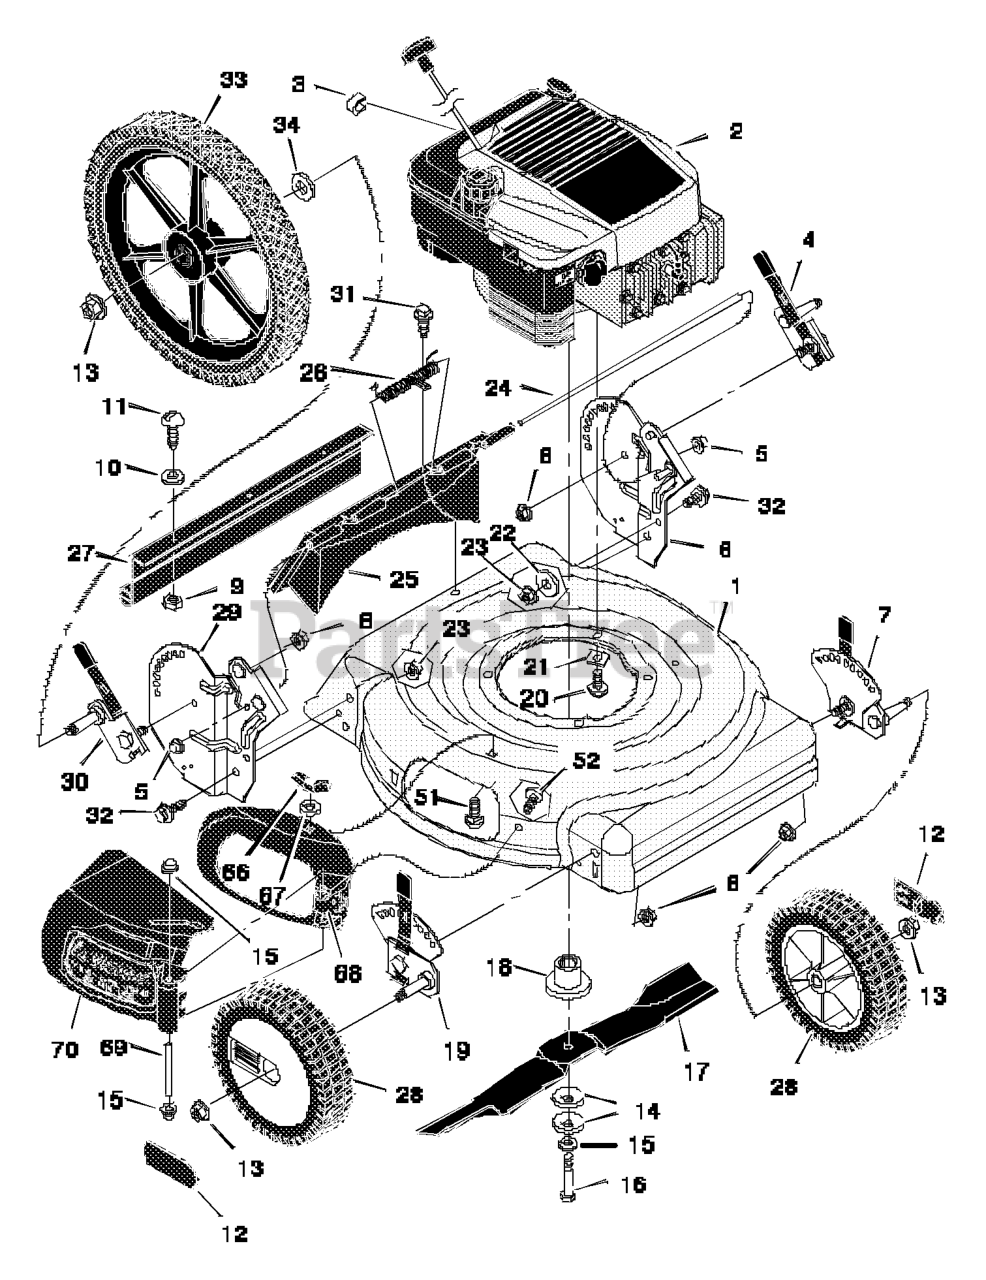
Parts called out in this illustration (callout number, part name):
1	Housing
2	Engine *
3	Stop, Rope (Recoil - Start)
4	Adjuster, Left Height
5	Push On Cap
6	Bracket, Left Handle
7	Adjuster, Left Front Height
8	Nut, Flange
9	Nut, Hex
12	Hub Cap
13	Nut, Flange
14	Washer, Belleville
18	Adapter, Blade
20	Bolt, Engine
21	Support, Engine
22	Washer
23	Nut, Flange
24	Rod, Pivot
25	Door, Rear
27	Guard, Rear
28	Wheel (Light Gray)
29	Bracket, Right Handle
30	Adjuster, Right Height
32	Bolt
33	Wheel, Rear
51	Bolt, Carriage
66	Wingnut
67	Retainer, Push
69	Pin, Pivot
70	Deflector, Chute
